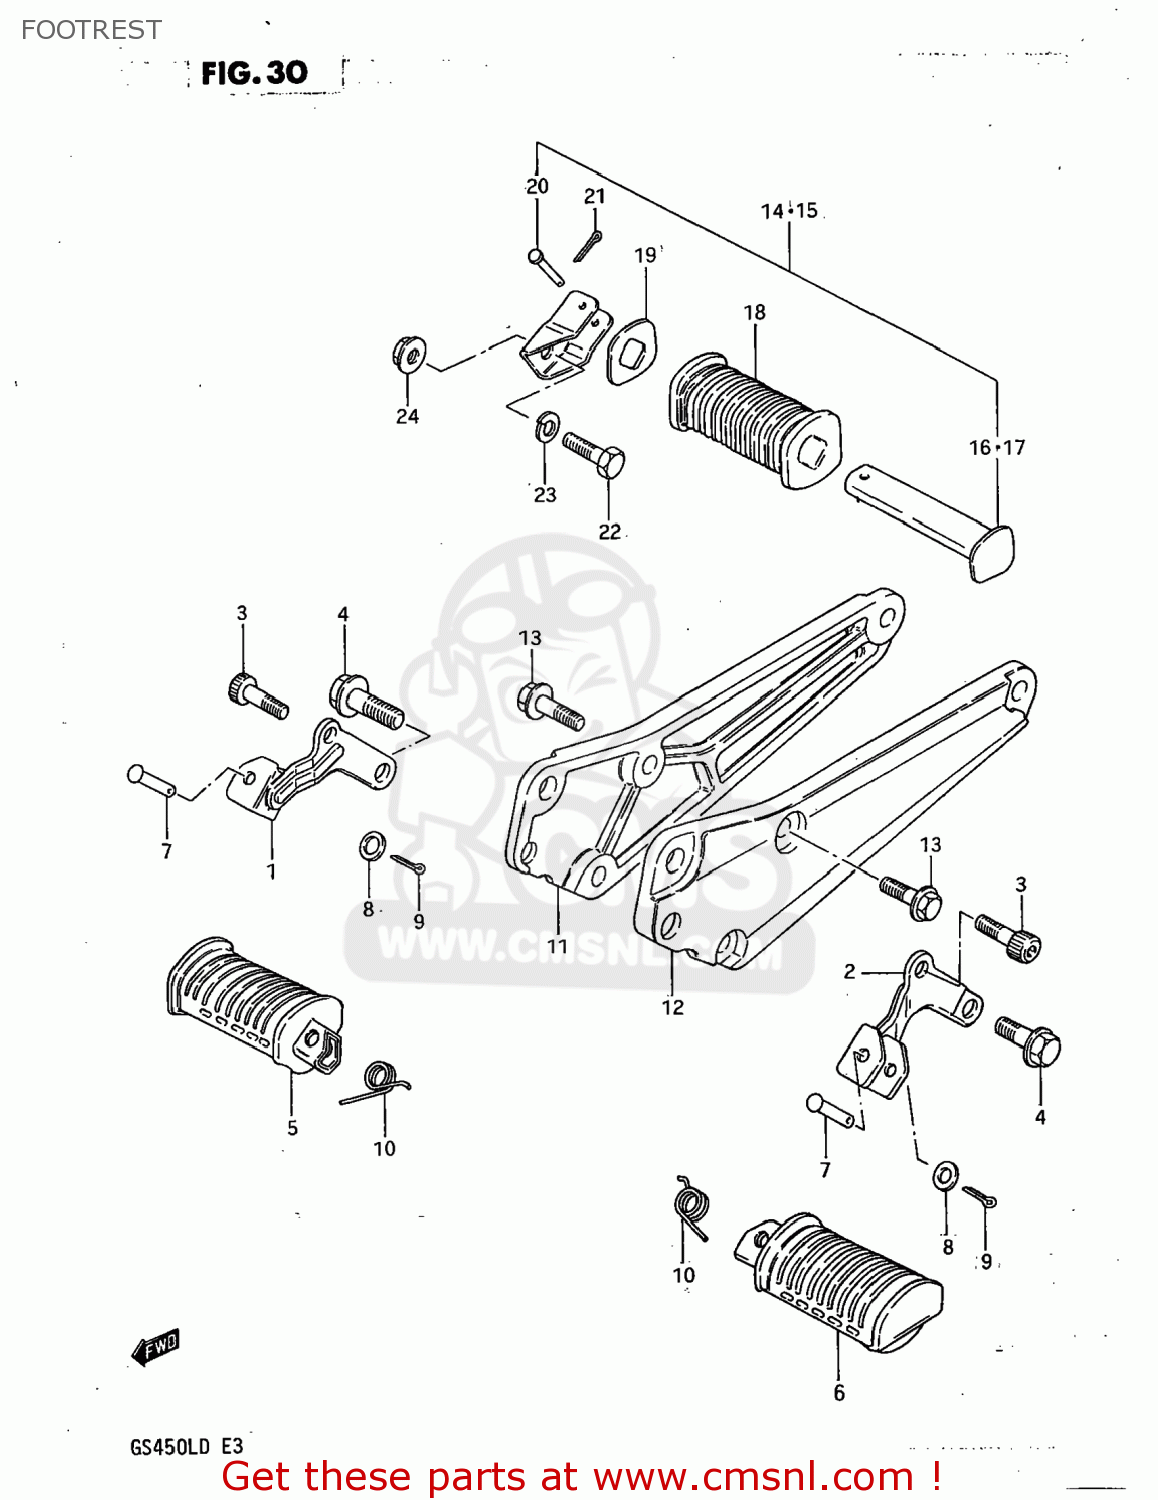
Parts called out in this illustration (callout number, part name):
1	BAR,FRONT FOOTREST,RIGHT
2	BAR,FRONT FOOTREST,LEFT
3	BOLT
4	BOLT
5	RUBBER,PILLION FOOTREST,R
6	RUBBER,PILLION FOOTREST,L
7	PIN
8	WASHER
9	PIN 20X20
10	SPRING
11	BRACKET,MUFFLER,RIGHT
12	BRACKET,MUFFLER,LEFT
13	BOLT
14	FOOTREST ASSY,PILLION,R
15	FOOTREST ASSY,PILLION,L
16	BAR,REAR FOOTREST,RIGHT
17	BAR,REAR FOOTREST,LEFT
18	RUBBER,PILLION FOOTREST
19	WASHER,FOOTREST RUBBER
20	PIN
21	PIN 20X20
22	BOLT,M10X1.25X
23	LOCK WASHER
24	NUT
